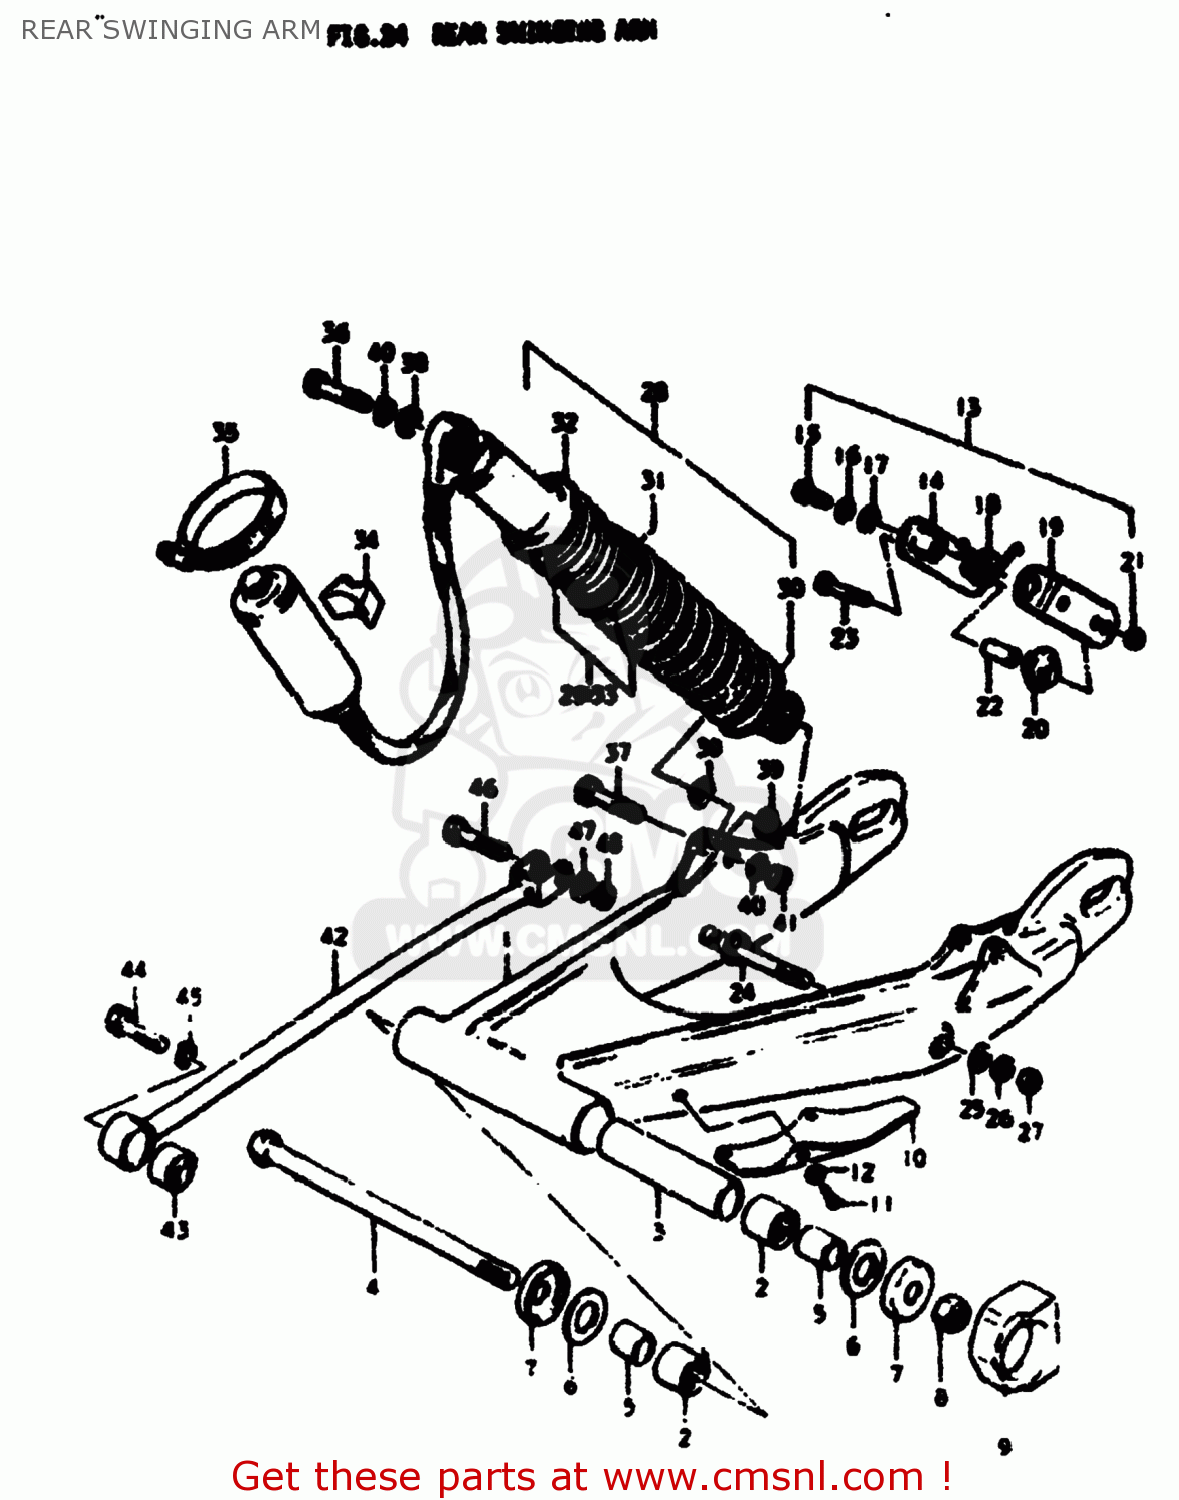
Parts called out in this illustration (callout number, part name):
1	SWING ARM ASSEMBLY,REAR
2	BEARING(22X29X20)
3	SPACER,REAR SWING ARM PIVOT
4	SHAFT,REAR SWING ARM
5	SPACER,RR SWGARM PIVOT
6	WASHER(14.2X34X1)
7	COVER,REAR SWING ARM DUST
8	NUT 14MM
9	BUFFER,CHAIN TOUCH DEFENSE
10	BUFFER,CHAIN TOUCH DEFLECTOR
11	SCREW
12	WASHER
14	TENSIONER,CHAIN
15	BOLT
16	LOCK WASHER
17	WASHER
18	SPRING
19	PLATE,CHAIN TENSIONER
20	RUBBER,CHAIN GUARD
21	NUT
22	SPACER(6.5X10.5X22.5)
23	BOLT
24	HOLDER,CABLE TENSIONER
25	WASHER
26	LOCK WASHER
27	NUT
28	ABSORBER ASSEMBLY,REAR SHOCK
31	SPRING
32	GUIDE,SPRING
34	CUSHION,RR SHOCK ABSORBER
35	CLAMP
36	BOLT 10X40
37	BOLT(10X48)
38	WASHER
39	WASHER
40	LOCK WASHER
41	NUT
42	LINK,REAR TORQUE
43	BUSH
44	BOLT 10X40
45	LOCK WASHER
46	BOLT 10X40
47	WASHER
48	NUT
